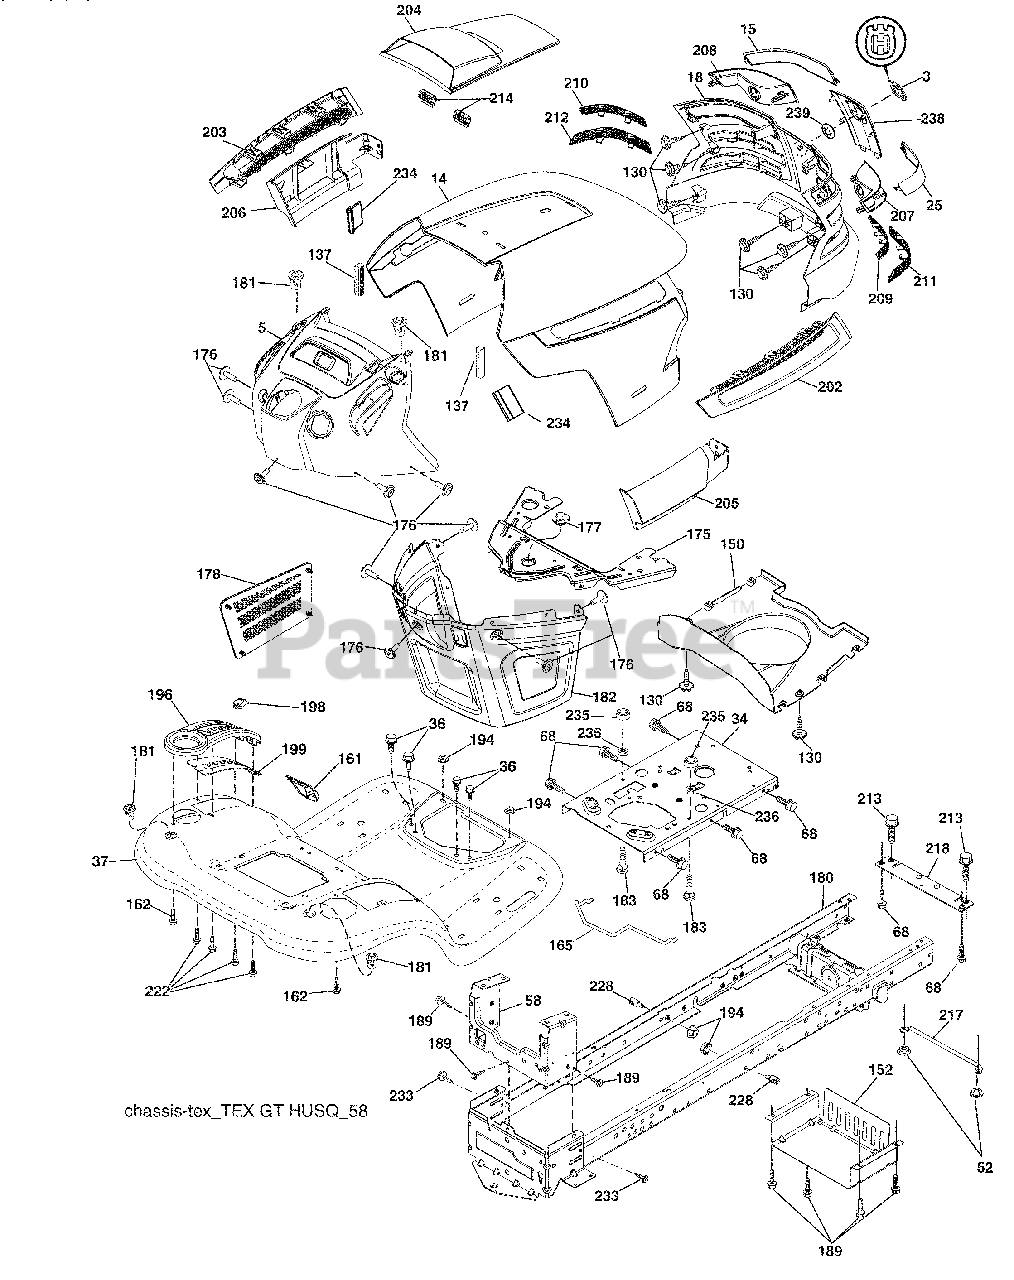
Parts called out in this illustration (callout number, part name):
3	Logo
14	Hood
18	Grille/Lens Asm.
34	Plate Engine
36	Screw 5/16-18 x 3/4
52	Nut Lock 5/16-18
58	Drawbar Upper
68	Screw Thdrol. 5/16-18 x 1/2
130	Screw #10 x 0.750
137	Bumper Dash
152	Shield Browning
161	Console Fuel Window
165	Support Tank Rear
175	Crossmember
176	Screw 10-24 x 5/8
177	Bushing Steering
178	Cargo Net Asm.
181	Bushing Mtg. Fender Crgo
182	Dash Lower
183	Bolt Fin. Hex 5/16-18 unc x 1-1/4
189	Screw 5/16-18 x 3/4
194	Nut Lock Hex Flange 5/16-18
196	Console Asm. Deck Lift
198	Indicator Deck Lift
199	Plate Deck Lift
202	Vent Side Hood RH
203	Vent Side Hood LH
204	Vent Top Hood
205	Skirt Hood Side RH
206	Skirt Hood Side LH
209	Insert Hex Top RH
210	Insert Hex Top LH
211	Insert Hex Bottom RH
212	Insert Hex Bottom LH
213	Bolt 5/16-18 x 3/4
214	Clip Retainer
218	X-Piece Hood Stop
222	Screw 1/4-20 x 5/8
228	Stud Fastner
233	Bolt Shoulder
234	Bumper Hood
235	Spacer Fender
236	Nut Lock 5/16-18 unc
